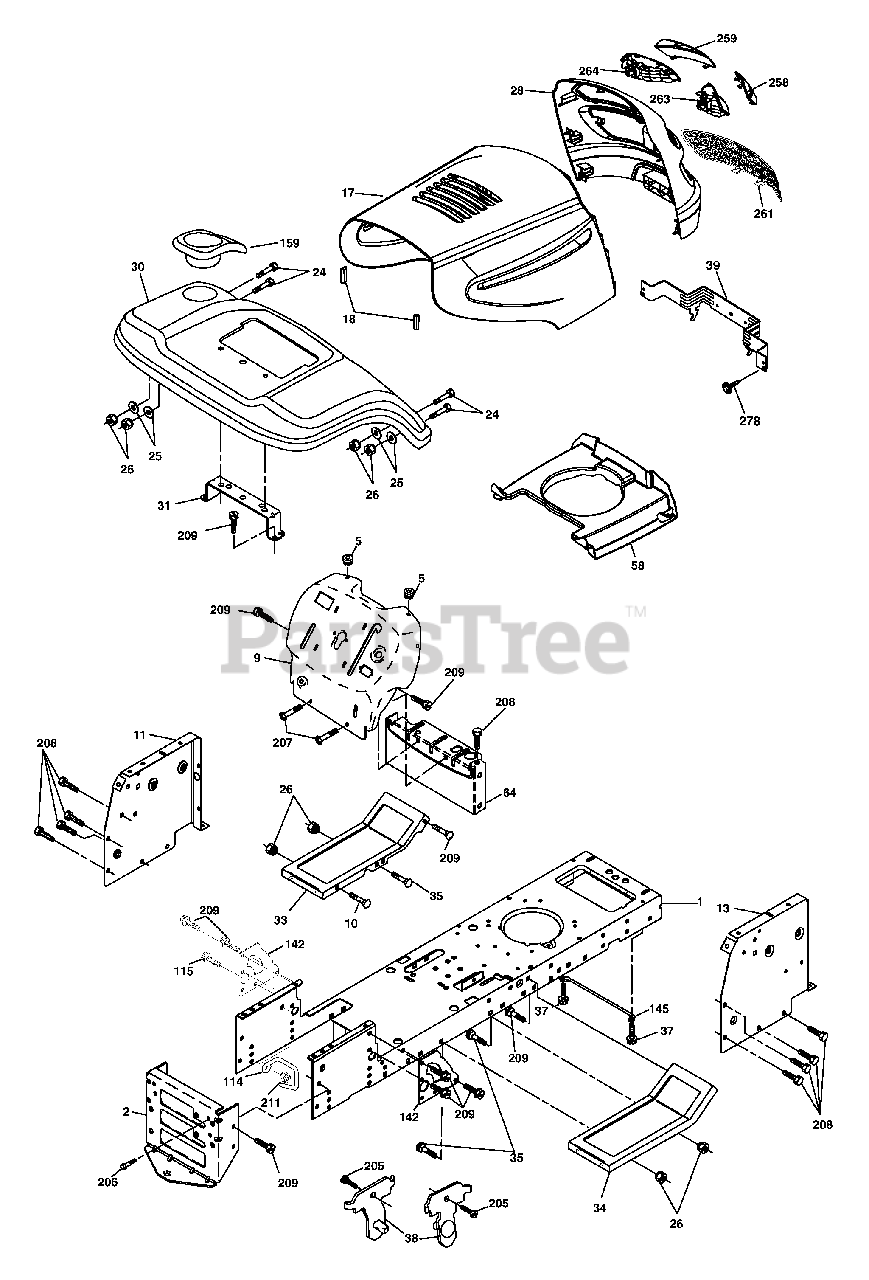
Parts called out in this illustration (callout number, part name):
1	Chassis
2	Drawbar
5	Bumper Hood/Dash
9	Dash
10	Bolt Carriage 3/8-16 x 1
11	Panel Dash Lh
17	Hood
18	Bumper Hood
24	Bolt Fin Hex 3/8-16 unc x 1 Gr. 5
25	Washer 13/32 x 13/16 x 12 Ga.
26	Nut Lock Hex W/Ins 3/8-16 unc
28	Grille/Lens Asm
30	Fender
31	Bracket Fender
33	Footrest LH
34	Footrest RH
35	Bolt RDHD SHT SQNK 3/8-16 x 3/4
37	Screw Thdrol 6/16-18 x 1/2 TYT
38	Bracket Asm Pivot Mower Rear
39	Bracket Pivot
58	Duct Air
64	Dash Lower STLT
114	Keeper Belt Rear LH
115	Screw THDROL 3/8-16 x 1-1/4
142	Plate Reinforcement STLT
145	Rod Pivot Chassis/Hood
159	Cupholder
205	Screw Thdrol 3/8-16 x 1/2
206	Bolt Shoulder 5/16-18
207	Screw Thdrol 3/8-16 x 1/2
208	Screw Thdrol 3/8-16 x 1/2
209	Screw Hexwsh Thdr 3/8-16 x 3/4
211	Nut Hex Flange Lock
258	Lens Grille Pro RH
259	Lens Grille Pro LH
263	Bezel Grille RH
264	Bezel Grille LH
278	Screw 10 x 3/4 Single Lead Hex
